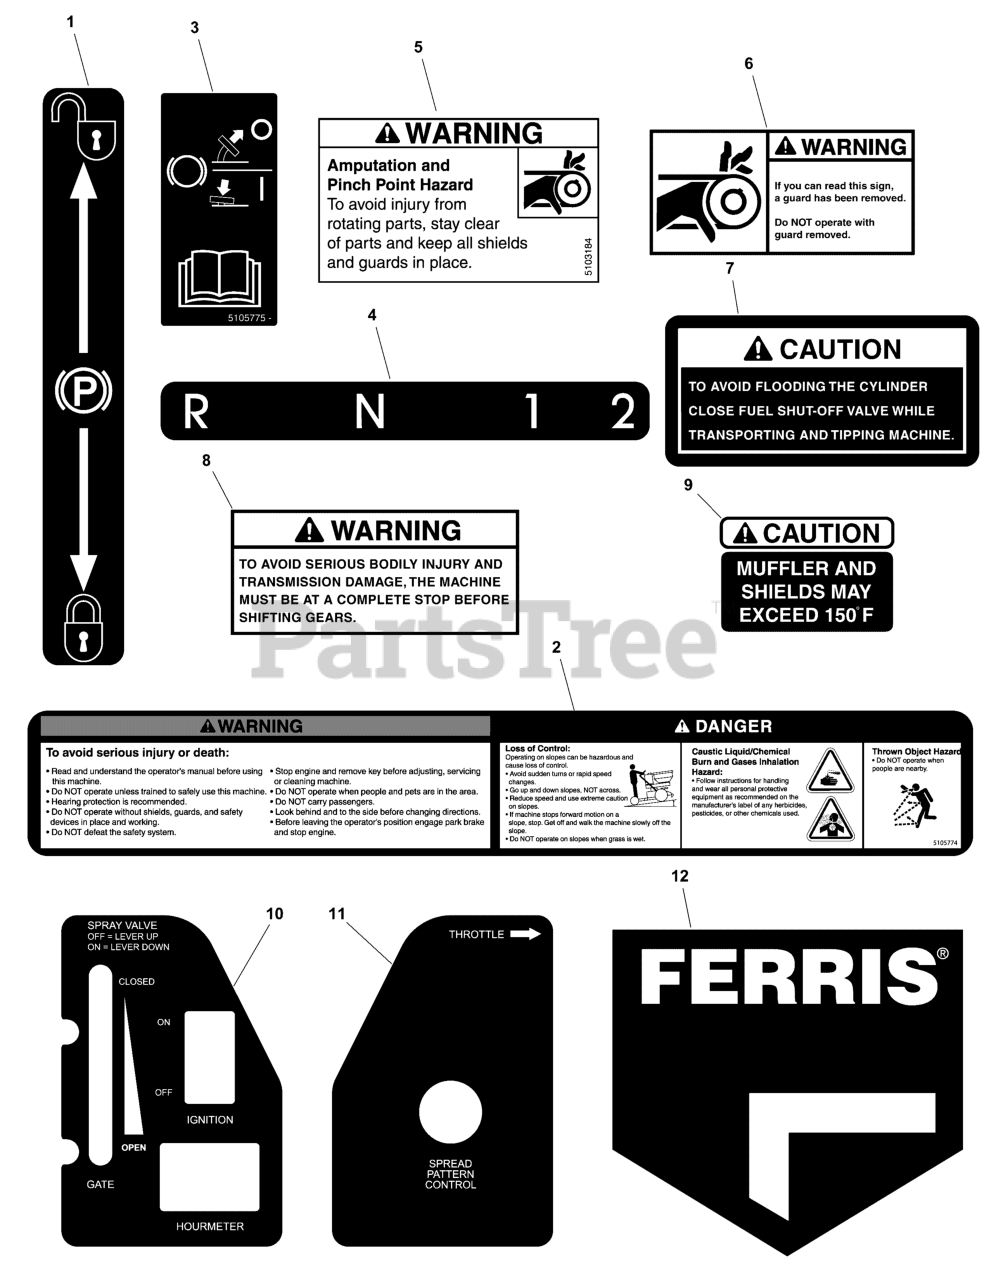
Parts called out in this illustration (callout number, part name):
1	DECAL, PARKING BRAKE SYMBOLS
2	DECAL, WARNING / DANGER
3	DECAL, BRAKE PEDAL
4	DECAL, GEAR SELECTOR
5	DECAL, WARNING, HAND IN BELT, ENG ONLY
6	DECAL, WARNING, GUARD
7	DECAL, CAUTION, FLOODING
8	DECAL, WARNING, INJURY & TRANS. DAMAGE
9	DECAL, CAUTION, MUFFLER TEMP.
10	DECAL, CONSOLE, LEFT ROVER
11	DECAL, CONSOLE, RIGHT ROVER
12	DECAL, 3.00" FERRIS SHIELD LOGO
